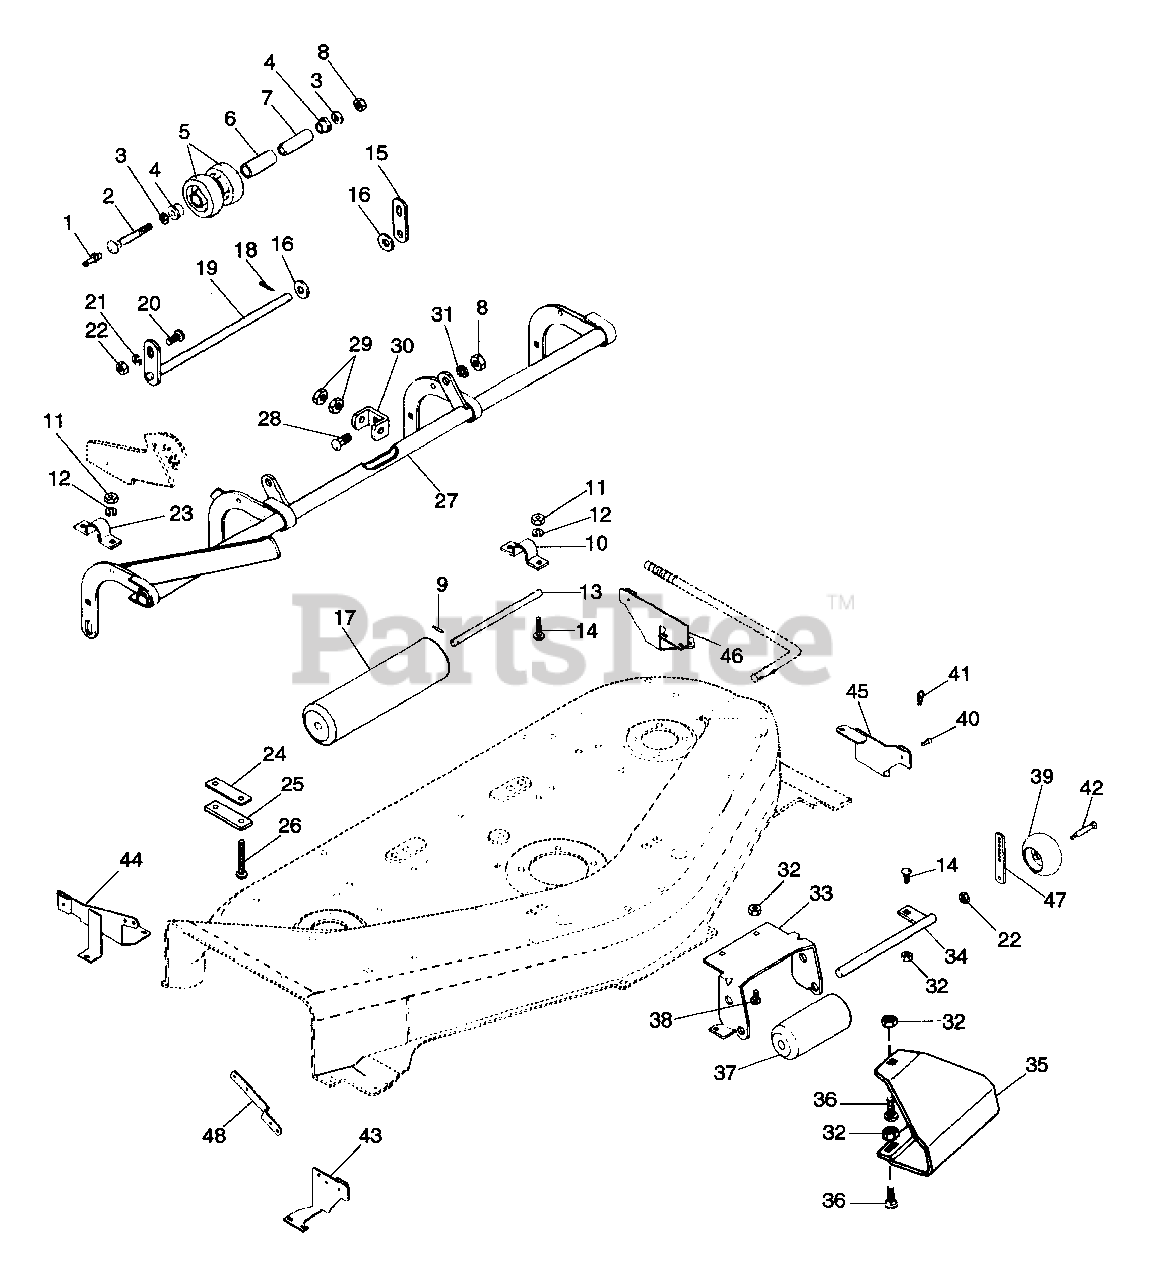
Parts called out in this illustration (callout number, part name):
1	SPIN DRIVE ZERK FITTING
2	WHEEL BOLT W/ZERK
3	WSHR-FL-STL .511X1.441X.125 PL
4	BRG-BALL .500X1.125X.500
5	WHL 5 IN O.D.
6	WHEEL HUB
7	SPACER .512X.747X3.396
8	NUT-LK-CTR .50-13
9	PIN-ROLL .250X1.00
10	ROLLER CLAMP
11	NUT-HEX .312-18
12	WSHR-LK .312X.097 PL HVY
13	SHAFT
14	BLT-RDHDSQNK .31-18X.75 GR5 PL
15	LINK
16	WSHR-FL-STL.656X1.312X.095 PL
17	ROLLER
18	PIN-COTR .18X1.0 PL
19	ROLLER SHAFT
20	BLT-RDHDSQSHNK .38-16X1.00 PL
21	WSHR-FL-STL .438X1.0X.083 PL
22	NUT-LK-CTR .375-16 GR A PL
23	CLAMP
24	ADJUSTMENT PLATE
24	PAD
25	ADJUSTMENT PLATE
26	BLT-RDHDSQNK .31-18X1.0 SHT PL
26	BLT-RDHDSQNK .31-18X1.38SHT PL
26	BLT-RDHDSQNK .31-18X2.75 SHPL
27	ROLLER FRAME
27	ROLLER FRAME 60
28	BLT-RDHDSQNK .50-13X1.25 PL
29	NUT .50-13 PL
30	YOKE
31	WSHR-FL-STL .505X.880X.072 PL
32	NUT-LK .312-18 GR A PL
33	BRACKET, ROLLER
34	ROLLER SHAFT
35	SKID 42 INCH MOWER
36	BLT-RDHDSQSHNK .31-18X.50 YZ
37	ROLLER
38	BLT-RDHDSQNK .312-18X.62 PL
39	WHEEL 5 X 3
40	CLEVIS PIN
41	PIN-HAIR INT .08X.18X1.18
42	BLT-SHLDR .38-16X2.50 GR5 PL
43	BRACKET,RIGHT FRONT
44	BRACKET,RIGHT REAR
45	BRACKET,LEFT FRONT
46	BRACKET, LEFT REAR - 1 PIECE
47	SLIDING BAR
48	BRACE
